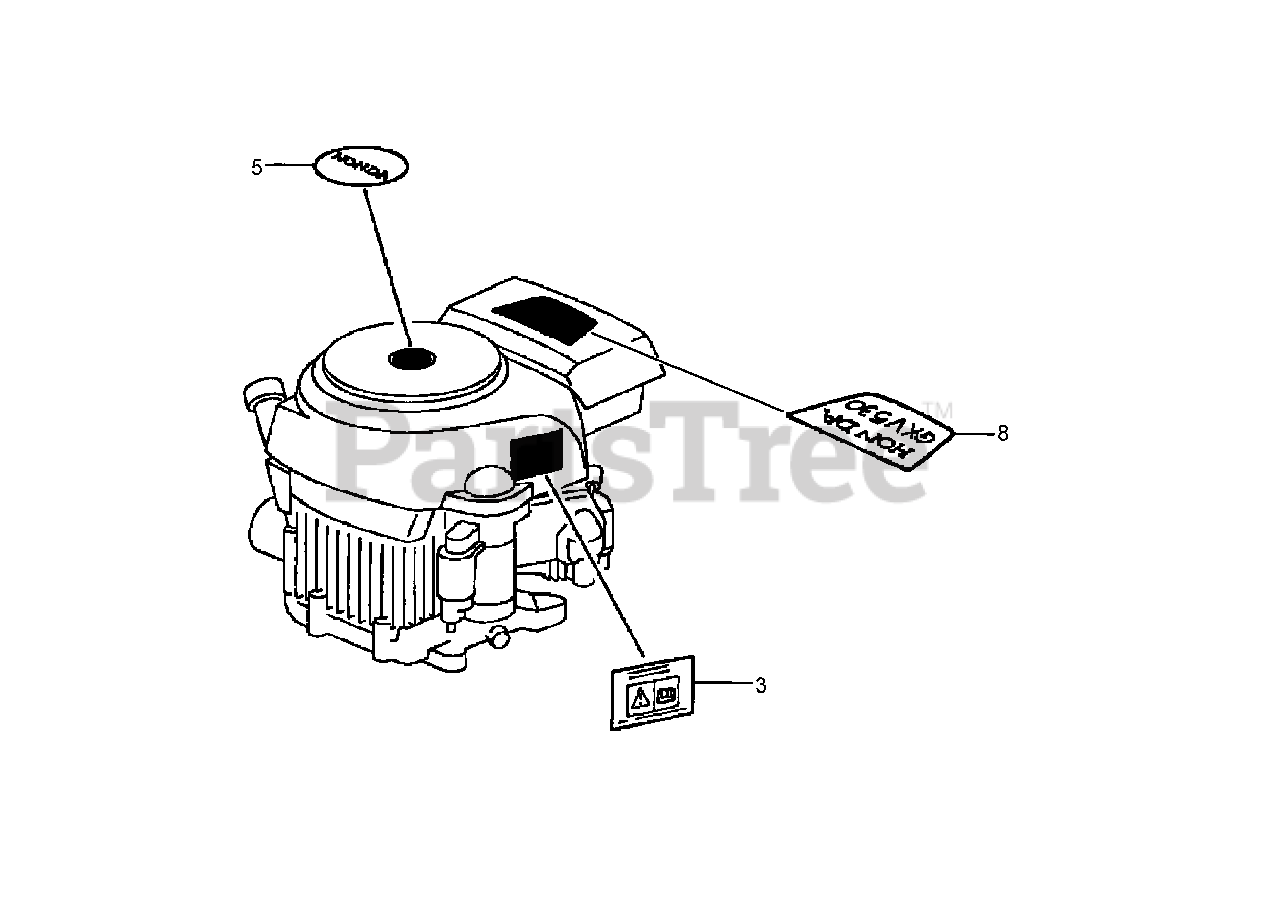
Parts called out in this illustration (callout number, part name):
3	MARK-CAUTION, OPERATOR
5	MARK-HONDA
8	MARK-EMBLEM (GXV530)
